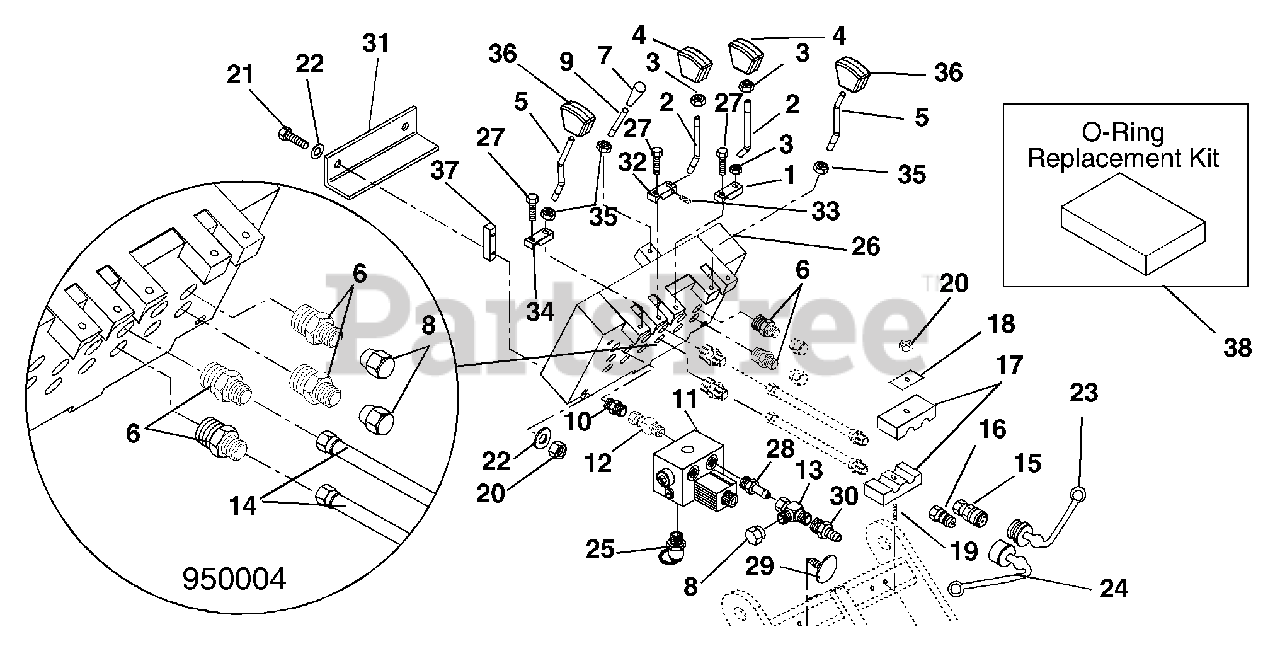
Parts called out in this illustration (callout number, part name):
1	Bracket, Left Hand Drive Lever
2	Lever-Direction Control
3	Nut-Jam M10-1.5
4	Knob-Control
5	Lever-Cylinder Control
6	Adapter, Face Seal 8 x 8 1/2 O-Ring
7	Knob-Control Lever
8	Fitting, Hydraulic Cap
9	Lever-Auxiliary Control
10	Fitting, Hydraulic Straight
11	Valve-Overcenter
12	Fitting, Hydraulic Straight Swivel
13	Fitting, Hydraulic Tee Swivel
14	Hose, Hydraulic .50-23-3K
15	Coupling, Female Quick-Orbit
16	Coupling, Male Quick-Orbit
17	Clamp-Dual Hose .500 I.D. Hose
18	Plate-Cover
19	Stud 8mm-1.25 x 3.62
20	Nut-Locking-Nylon M8-1.25
21	Bolt-Hex M8-1.25 x 65
22	Washer-Flat-Steel .39 x .75 x .125
23	Plug-Dust .50
24	Cap-Dust .50
25	Coupling-Test Port
26	Valve, Bank-Salami
27	Bolt-Hex M8-1.25 x 20
28	Fitting, Hydraulic Straight
29	Retainer-Trim
30	Swivel, Female Seal
31	Shield, Valve Heat
32	Bracket, Right Hand Drive Lever
33	Screw-Set .25-20 x .25
34	Bracket, Cylinder Control Lever
35	Nut, Jam M8-1.25
36	Knob, Control
37	Spacer, Valve Salami
38	(Assorted O-Rings for Hydraulic Components to fittings) SAE
38	(Assorted O-Rings for Flat Face Seal Fittings and Hoses)
